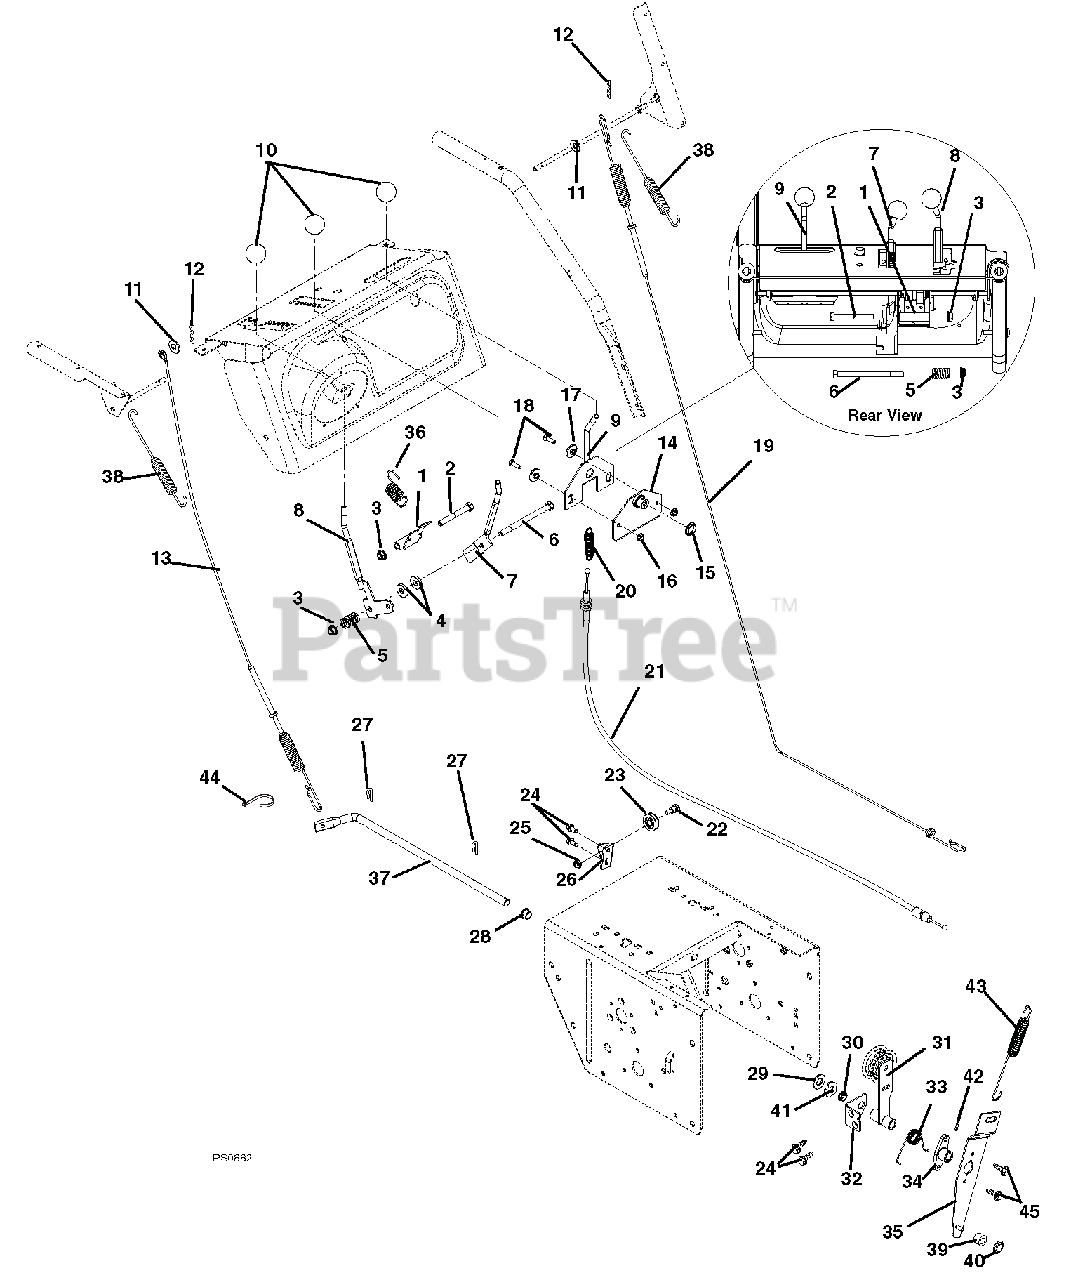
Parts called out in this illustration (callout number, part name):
1	ARM, INTERLOCK
2	@BLT-HEX .38-16X3.00 GR5 YWZC
3	@NUT-LK-TOP-FLG .38-16 YWZC
4	WSHR-FL-STL .406X1.00X.188 YWZ
5	SG-COMP .125X.781X1.250
6	@BLT-HEX .38-16X5.00 GR5 YWZC
7	CONTROL, DEFLECTOR
8	LEVER, SHIFT
9	LEVER, CHUTE CONTROL
10	KNOB,BALL -BLACK 1.47" .375-16
11	@WSHR-FL-STL.281X.62X.065 YWZC
12	PIN-HAIR INT .06X.18X.77
13	CABLE, ATTACHMENT
14	MOUNT, CHUTE CONTROL
15	BUSHING, POLYLINER-.75 SNAPIN
16	@NUT-LK-TOP-FLG .25-20 YWZC
17	BSHG-FLG .265X.448X.243X1.00
18	@BLT-HEX .25-20X.75 GR5 YWZC
19	CABLE, TRACTION
20	SG-TENS .048X.44X1.75 WLD 9
21	CABLE, CHUTE LOCK
22	BOLT, SHLDR-.375X.375X.25-20
23	PULLEY, CABLE
24	SCR-TAP .25-20X.50 HWH TR YWZ
25	@NUT-LK-TOP-FLG .25-20 YWZC
26	BRACKET, CABLE PULLEY
27	CLIP, SPRING
28	BUSHING, POLYLINER-.50 SPLIT
29	@WSHR-FL-STL.531X1.06X.095YWZC
30	BUSHING, POLYLINER-.50 SNAPIN
31	ARM, IDLER-TRACTION
32	BRACKET, SUPPORT
33	SG-TORS .067X.88
34	HUB, BRAKE ARM
35	ARM, IDLER-ATTACHMENT
36	SPRING-EXT .047X.438X1.45
37	ARM, ATTACHMENT
38	SG-TENS .056X.60X4.40
39	BSHG,SLV .270 X .750 X .250
40	RG-RTNG-EXT .250X.010
41	WAVE WASHER .531X.781X.125FH
42	PIN-ROLL .125X1.00
43	SG-TENS .06X.482X5.35
44	CABLE TIE LG 5-1/2
45	SCR-TAP .25-20X.75 HWH TR YWZ
45	SCR-TAP .25-20X.50 HWH TR YWZ
